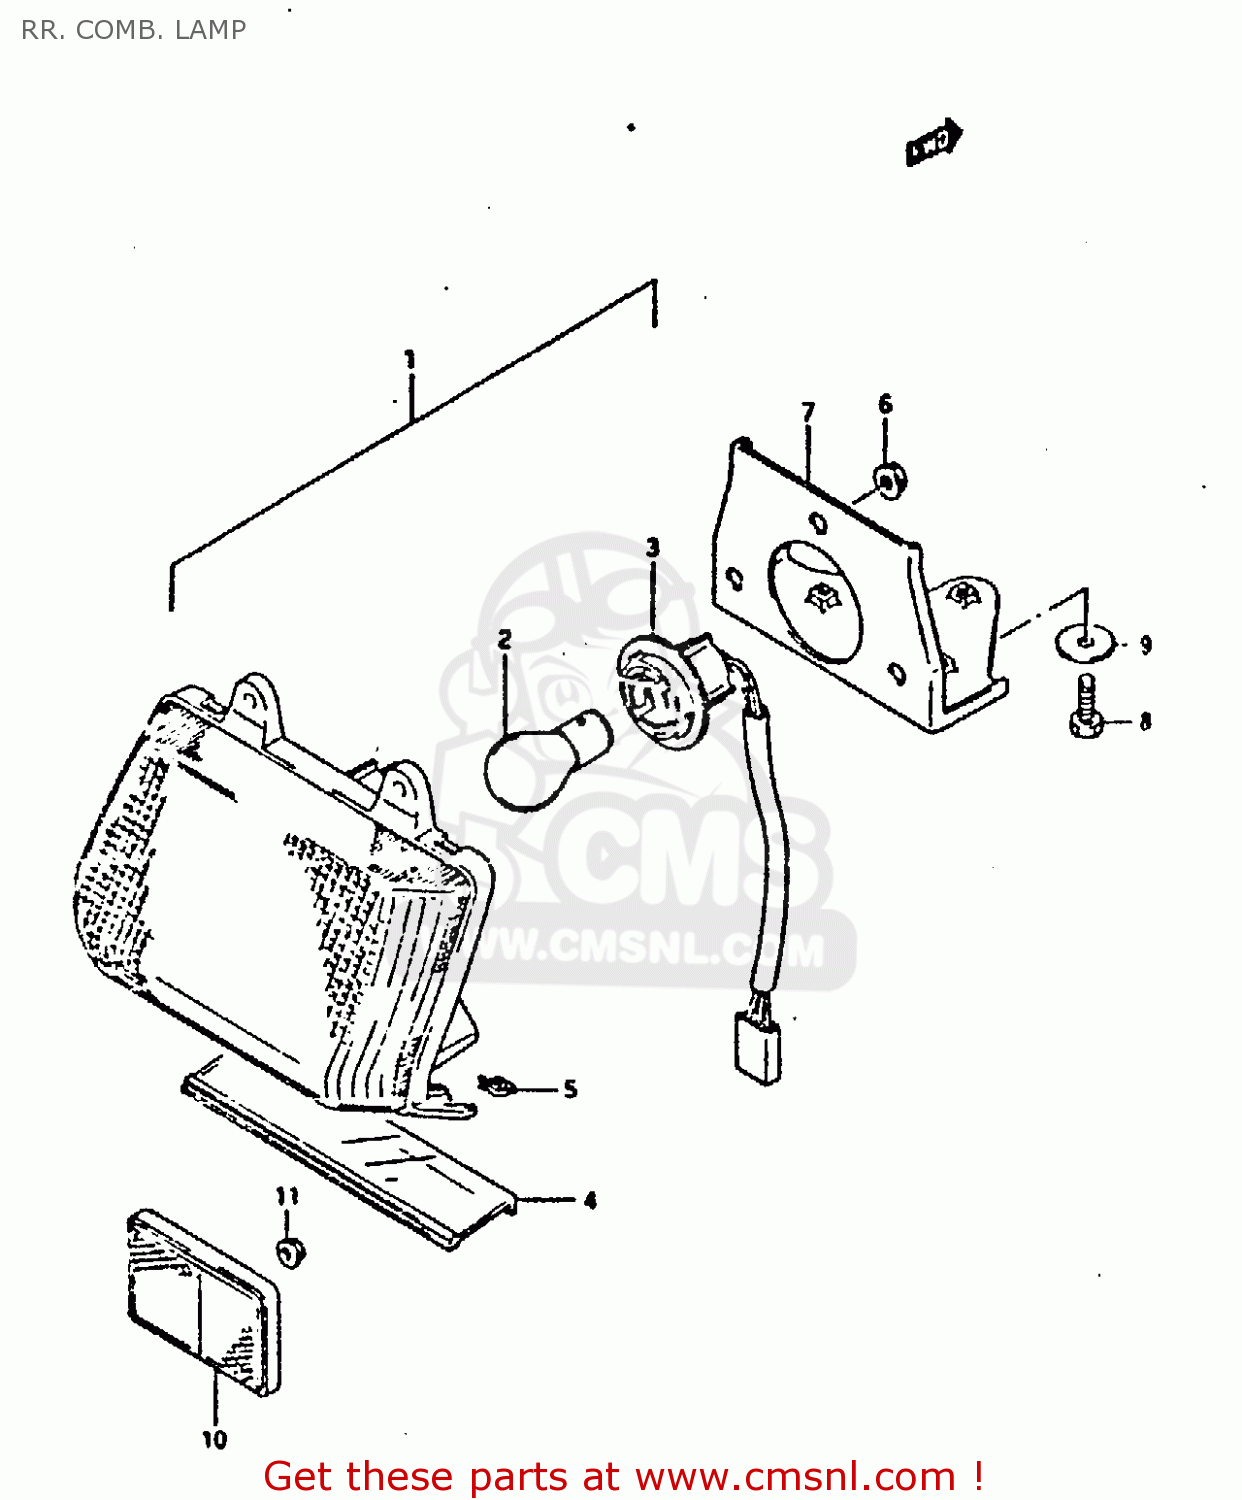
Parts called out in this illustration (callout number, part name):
1	LAMP ASSY,REAR COMB
2	BULB(12V21/5W)
3	SOCKET & CORD ASSEMBLY
5	NUT
6	NUT
8	BOLT,M6X1X20
9	WASHER
10	REFLEX REFLECTOR,RR
11	NUT
